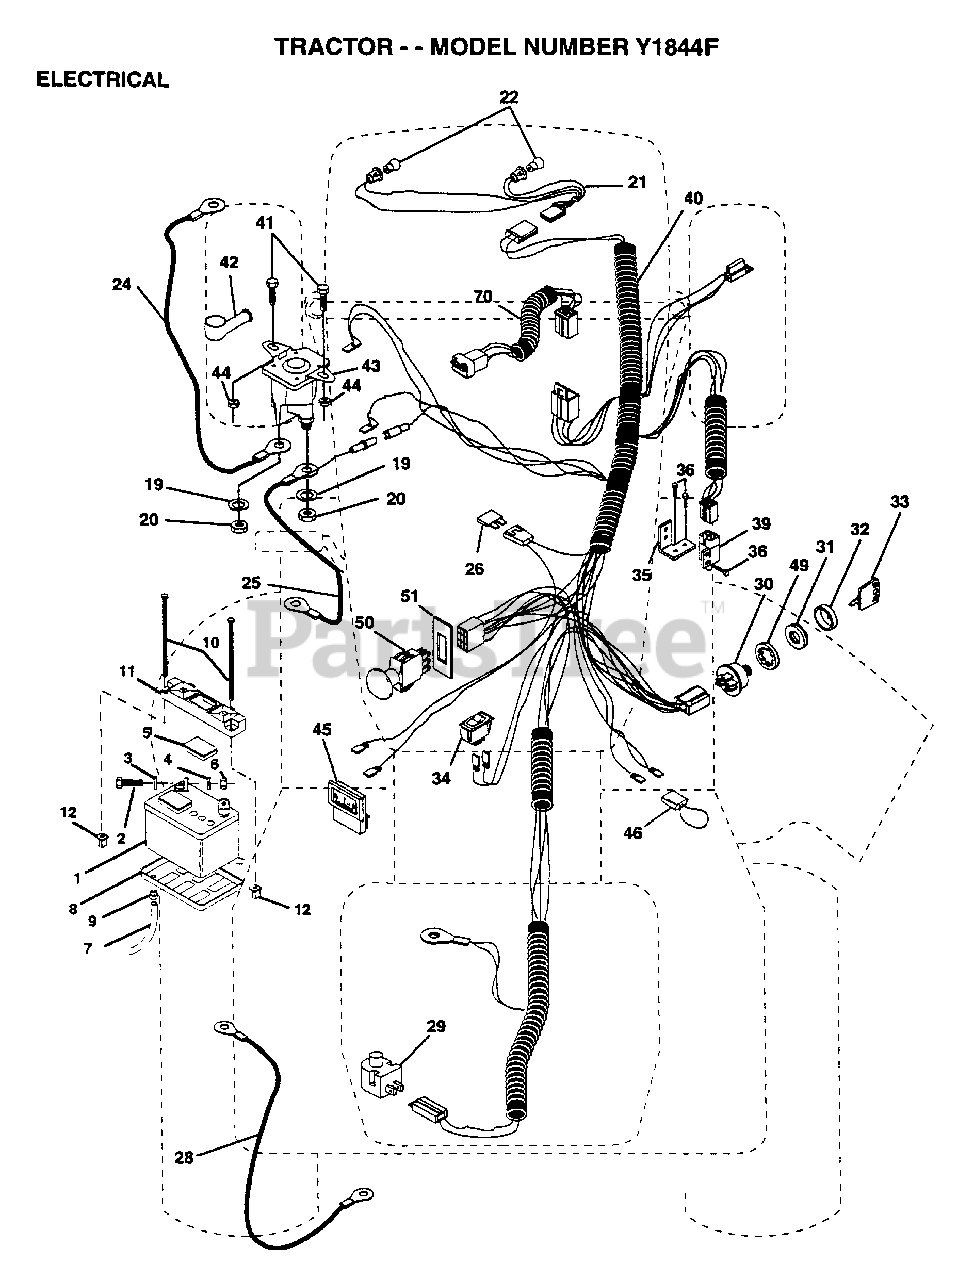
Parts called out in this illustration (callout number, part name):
2	BOLT LT
3	WASHER
4	LOCKWASHER
5	"CAP,BATTERY "
7	"DRAIN TU T, BATT"
8	"TRAY T, BATTERY"
9	HOSE CLAMP T
20	NUT
21	"HARNESS,LIGHT SOC"
22	HEADLAMP BULB
24	"CABLE T, BATTERY"
25	CABLE.6GA.22W/16W
26	FUSE HYT
28	CABLE.GRND.6GA.21
29	SWITCH SEAT
32	COVER KEY SWITCH
33	KEY MLD GEN DELTA
34	SWITCH LT
35	BRACKET LT
36	SCREW
39	SWITCH INTERLOCKT
40	HARNESS.ING.ELEC.
41	BOLT.HX.1/4-20
44	NUT
45	AMMETER
46	PROTECTION LOOP
49	LOCKWASHER
51	RING RETAIN PTO
70	HARNESS.ENG.KOHL
